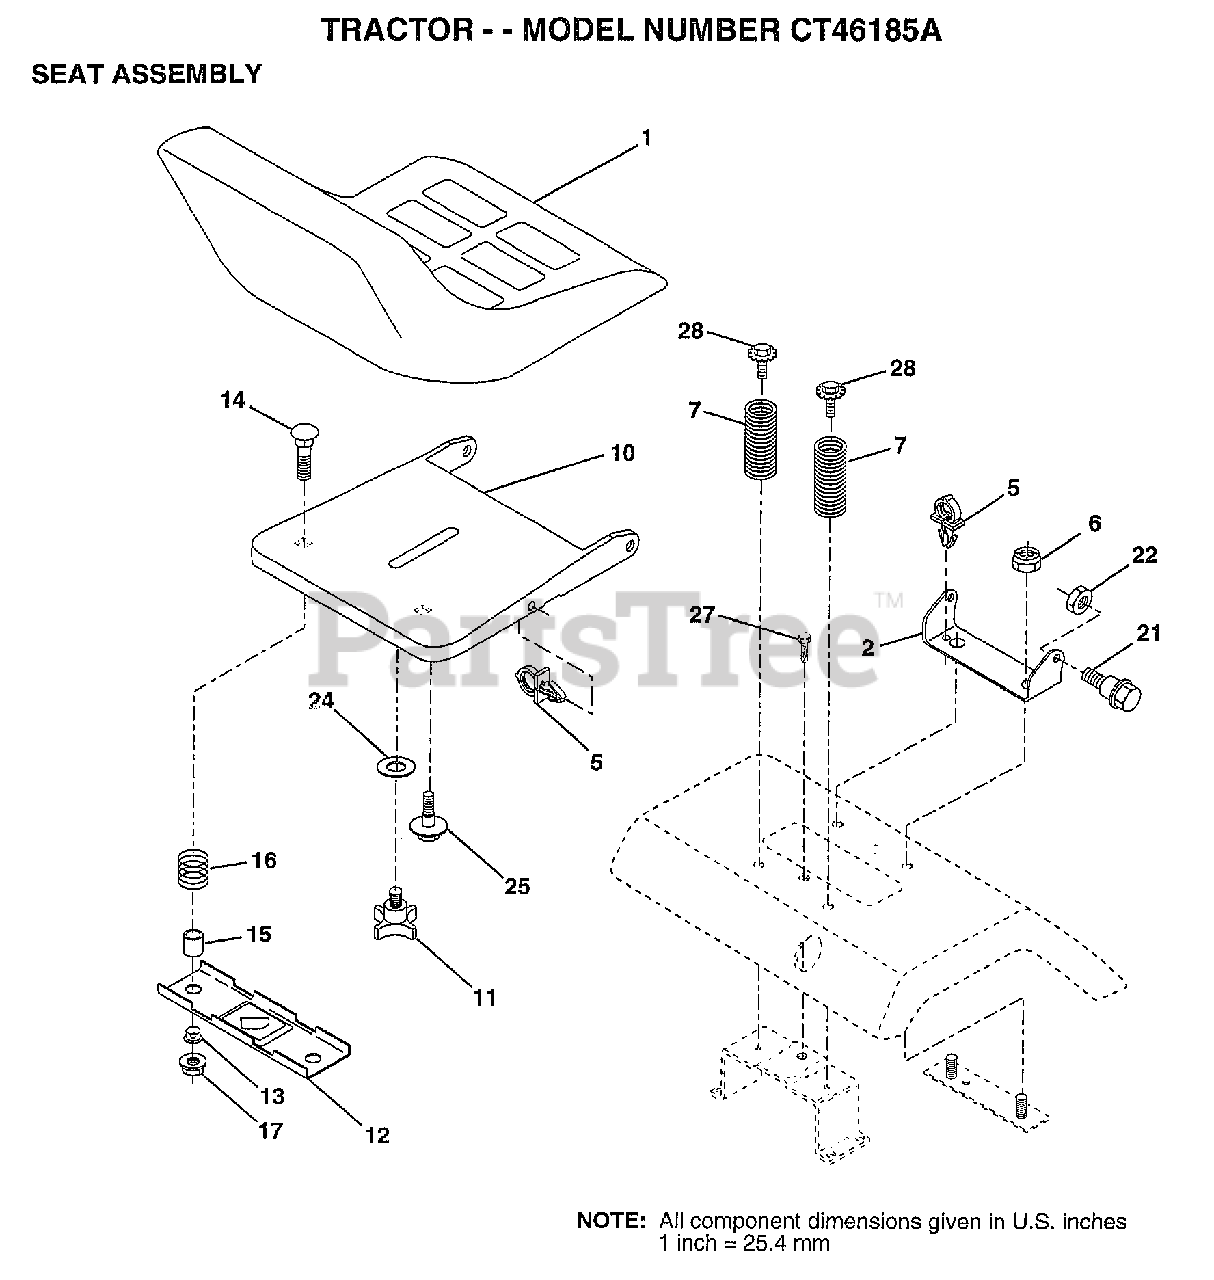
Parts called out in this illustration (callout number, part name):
2	BRACKET PVT SEAT
5	CLIP.PUSH-IN.HING
6	NUT
7	SPRING COMPRESSIO
10	PAN-SEAT
11	"KNOB 1/2"" YT"
12	BRKT SWITCH
13	BUSHING
14	BOLT-RD HD SQ NK
15	SPACER SPLIT
16	SPRING COMPRESSED
21	"BOLT,SHOULDER"
24	WASHER
25	"BOLT,SHOULDER"
27	SCREW LT
28	BOLT.5/16-18.UNC
